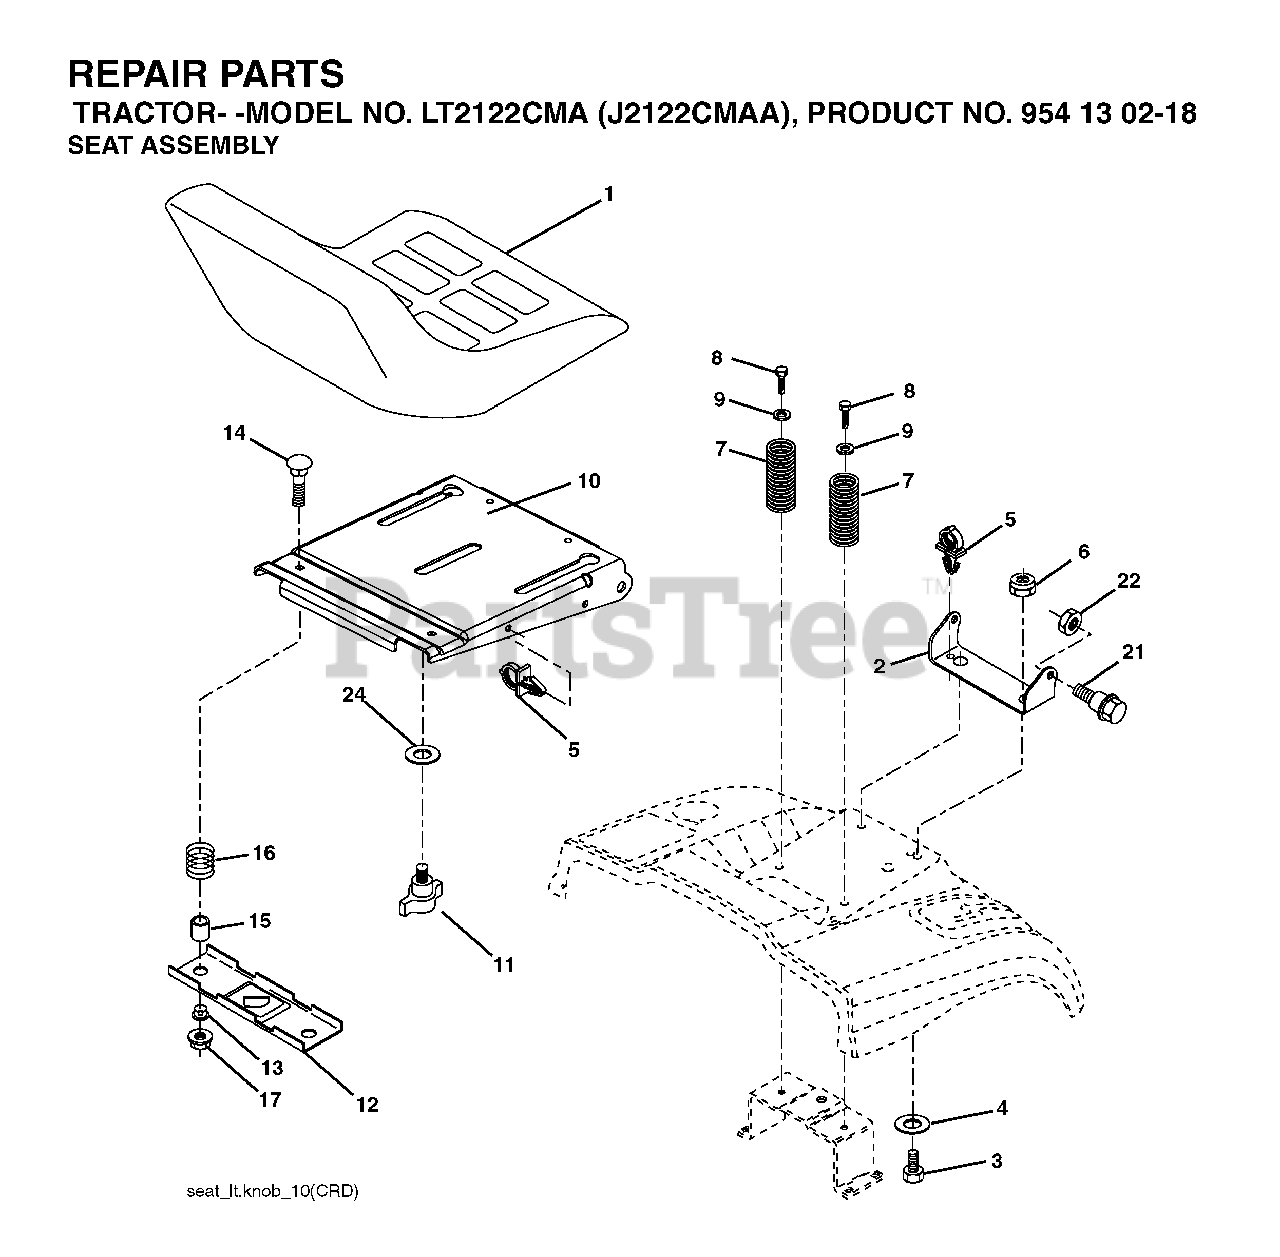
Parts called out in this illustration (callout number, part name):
2	BRKT.PIVOT.FENDER
4	WASHER PM
5	PUSH CLIP
6	NUT
7	SPRING COMPRESSION
8	SCREW 3/8-16X1
9	WASHER
11	KNOB.SEAT.ADJ.WINGNUT
12	BRKT SWITCH
14	BOLT.ROUND.HEAD.SQUARE.NECK
15	SPACER SPLIT
16	SPRING COMPRESSED
17	NUT T
21	BOLT.SHOULDER.5/16-18
22	NUT.71038.31-18.HEX.NYLOCK
